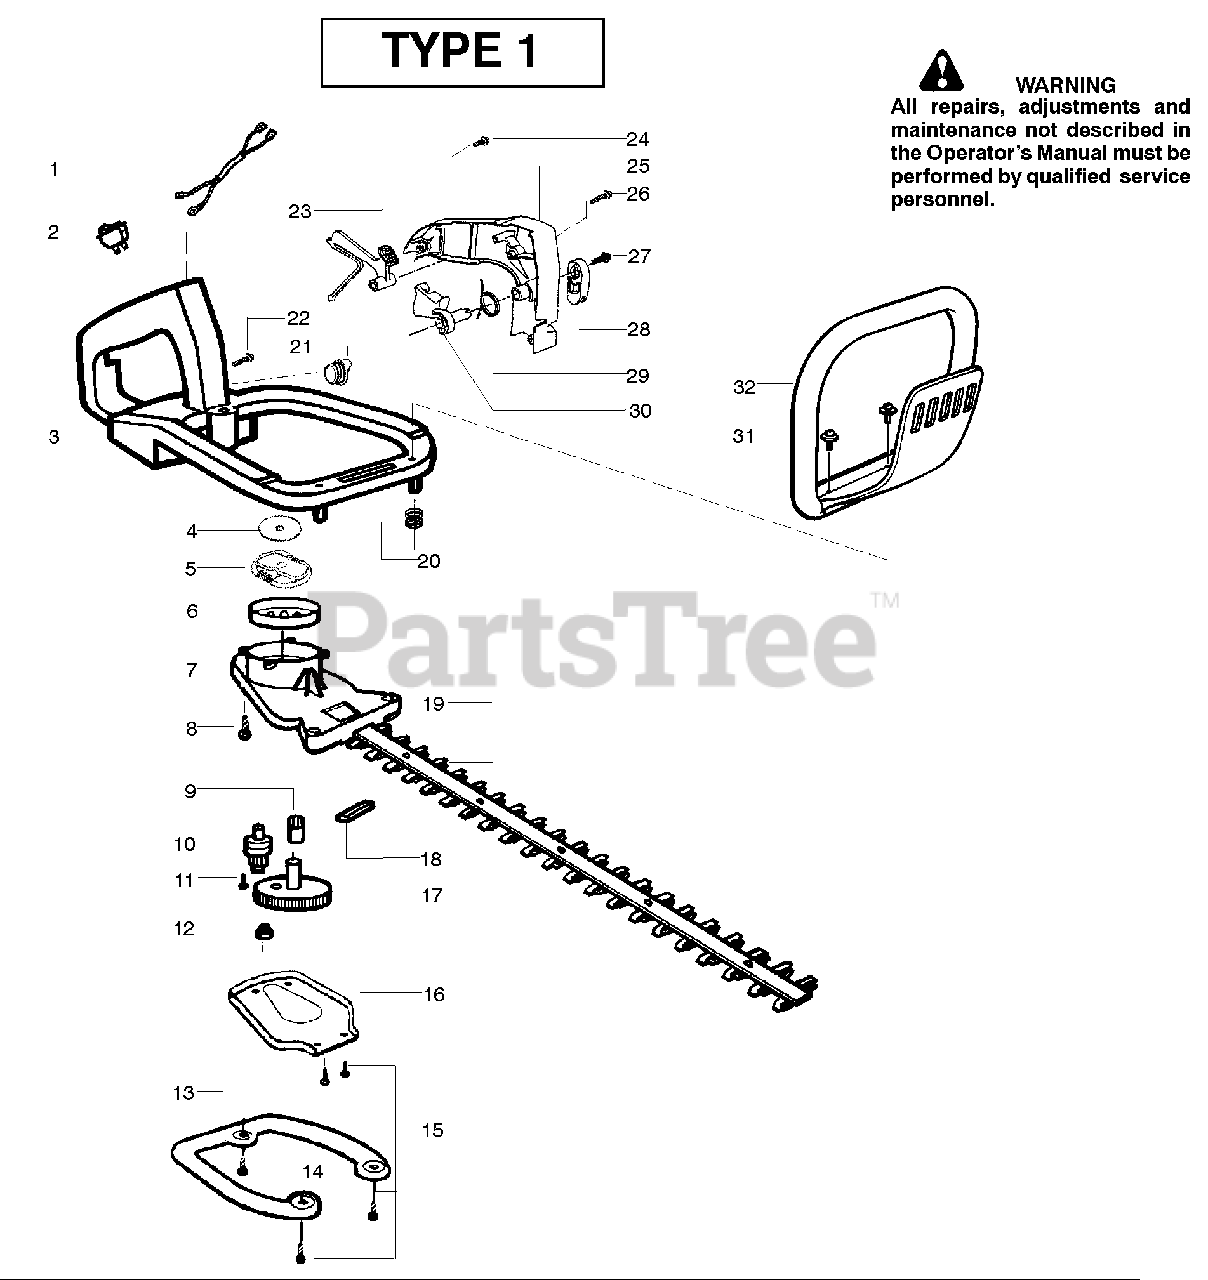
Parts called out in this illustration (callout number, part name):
1	Assy-Leadwire/Switch
2	Switch-Ignition
3	Assy-Rear Handle & Tank
4	Washer-Clutch (Kit)
5	Assy-Clutch (Kit)
6	Drum-Clutch (Kit)
7	Assy-Gear Box
9	Bearing-Gear
10	Assy-Pinion
11	Screw
12	Bushing-Blade
13	Plate-Isolator
16	Cover-Gear Box Plate
17	Kit-Drive Gear Ass'y.
18	Seal-Blade (Felt)
19	Assy-Blade 22"
21	Assy-Fuel Cap
23	Lockout-Throttle
25	Cover-Handle
28	Lever-Trigger
29	Spring-Trigger
32	Handle-Front
